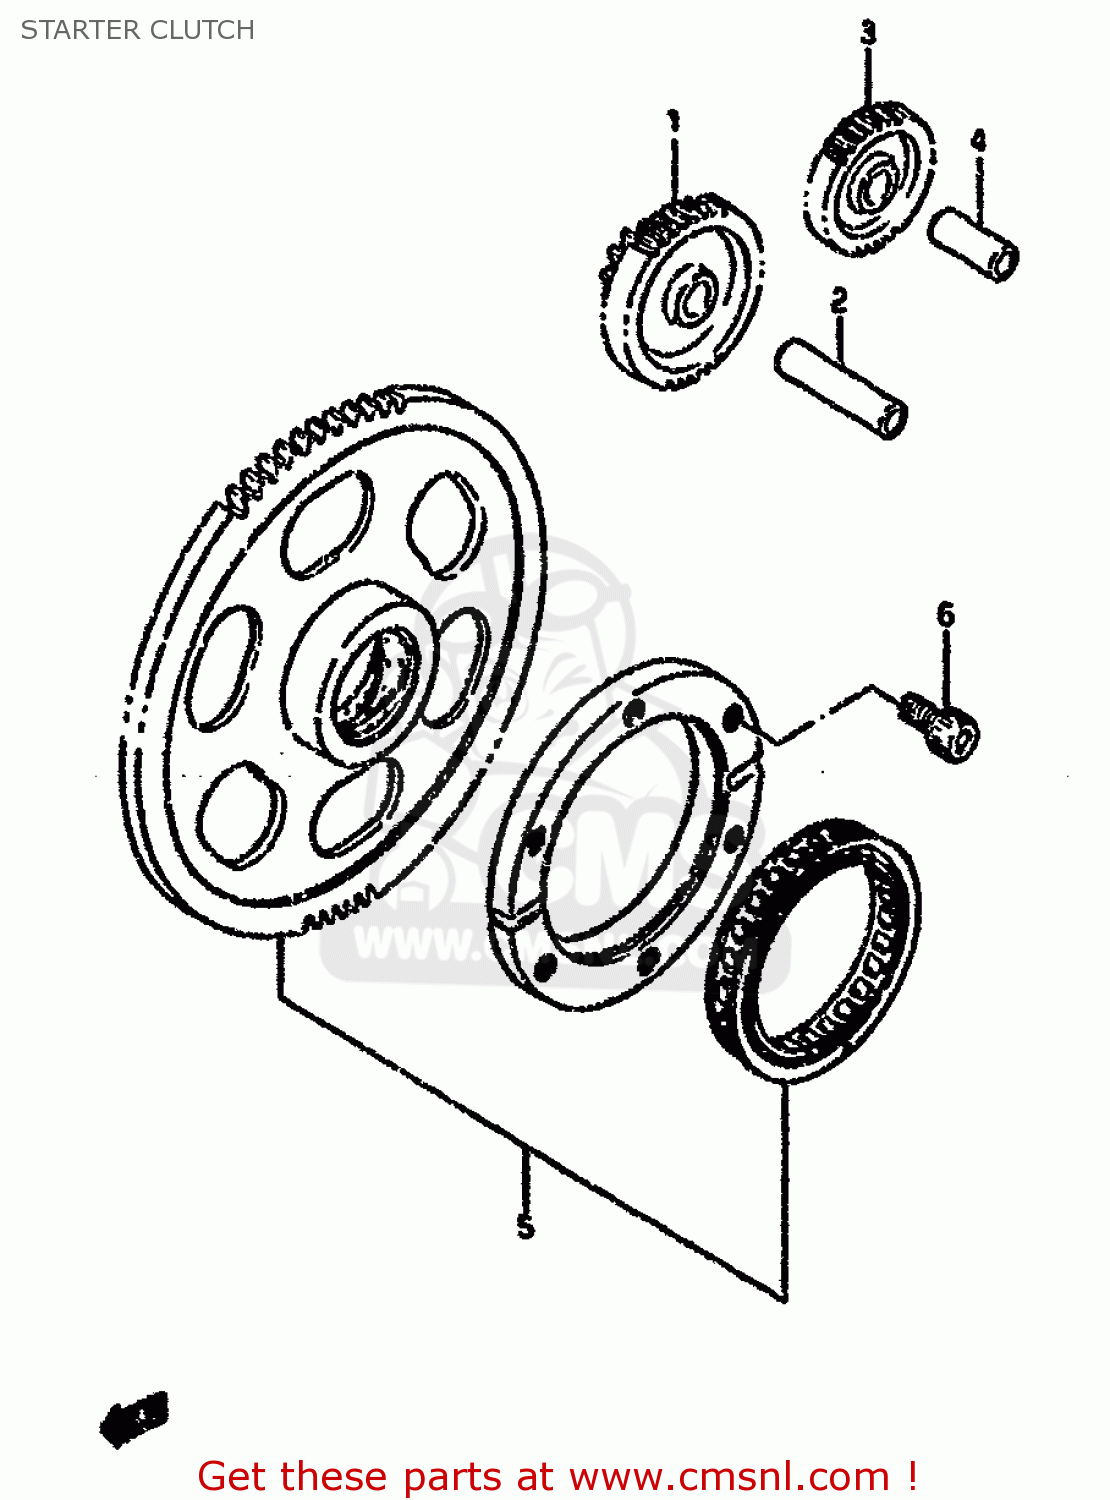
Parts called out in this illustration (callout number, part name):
1	GEAR,STARTER IDLE NO.1
2	PIN
3	GEAR,STARTER IDLE NO.2
4	PIN
5	CLUTCH SET,STARTER
6	BOLT
